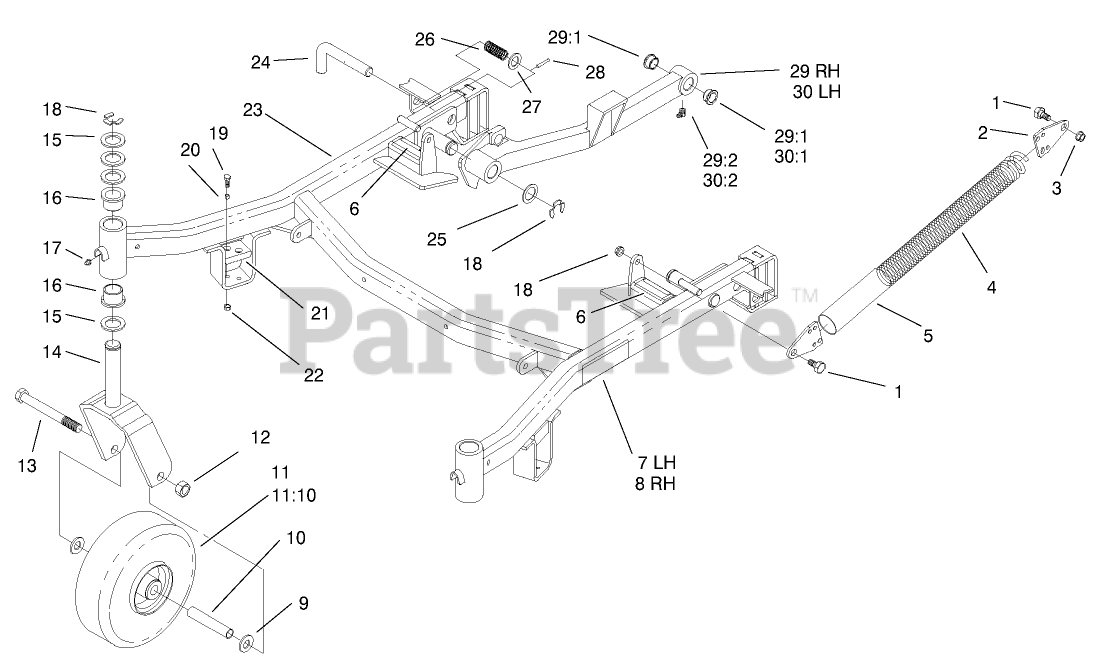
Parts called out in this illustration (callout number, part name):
1	BOLT-SHOULDER
2	PLATE-END, SPRING
3	NUT-LOCK, NI
4	SPRING-EXTENSION
5	COVER-SPRING
6	DECAL-WARNING
7	DECAL-HOC, LEFT
8	DECAL-HOC, RIGHT
9	WASHER-FLAT
10	SPANNER
11	WHEEL/TIRE ASM
12	NUT-HEX
13	SCREW-HH
14	FORK-CASTOR
15	WASHER-THRUST
16	BUSHING
17	FITTING-GREASE
18	RING-RETAINING
19	SCREW-HH
20	SPACER
21	CUSHION-RUBBER
22	NUT-LOCK, NI
23	FRAME-CARRIER
24	PIN - PIVOT
25	Washer
26	SPRING-COMPRESSION
27	WASHER
28	PIN-ROLL
29	RH PUSHARM ASM
29:1	BEARING-FLANGE
29:2	FITTING-GREASE
30	LH PUSHARM ASM
30:1	BEARING-FLANGE
30:2	FITTING-GREASE
